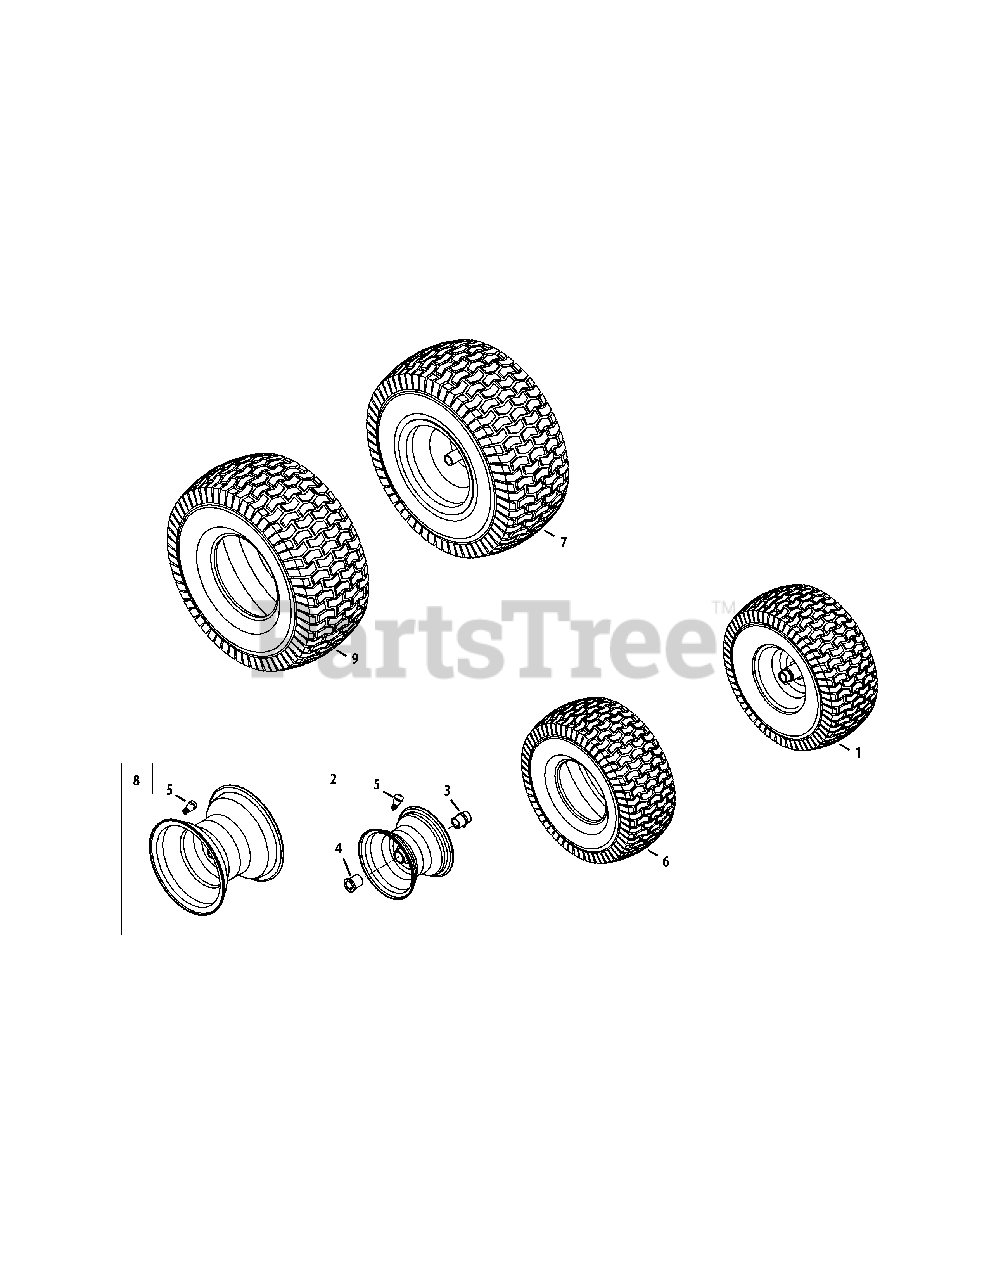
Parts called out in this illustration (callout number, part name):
1	Wheel Ass’y, Complete, 15 x 6 x 6
2	Rim Ass’y, 6.0 x 4.5, with Bearings
3	Bearing, Flange, .760 ID w/ Fitting
4	Bearing, Flange, .760 x 1.00 x 1.20
5	Valve, Tubeless Air
6	Tire, 15 x 6 x 6 Sq Shoulder
7	Wheel, Complete, 20 x 8 x 8
8	Rim Ass’y, 8.0 x 7.0 x .750 ID
9	Tire, 20 x 8 x 8 Sq Shoulder
